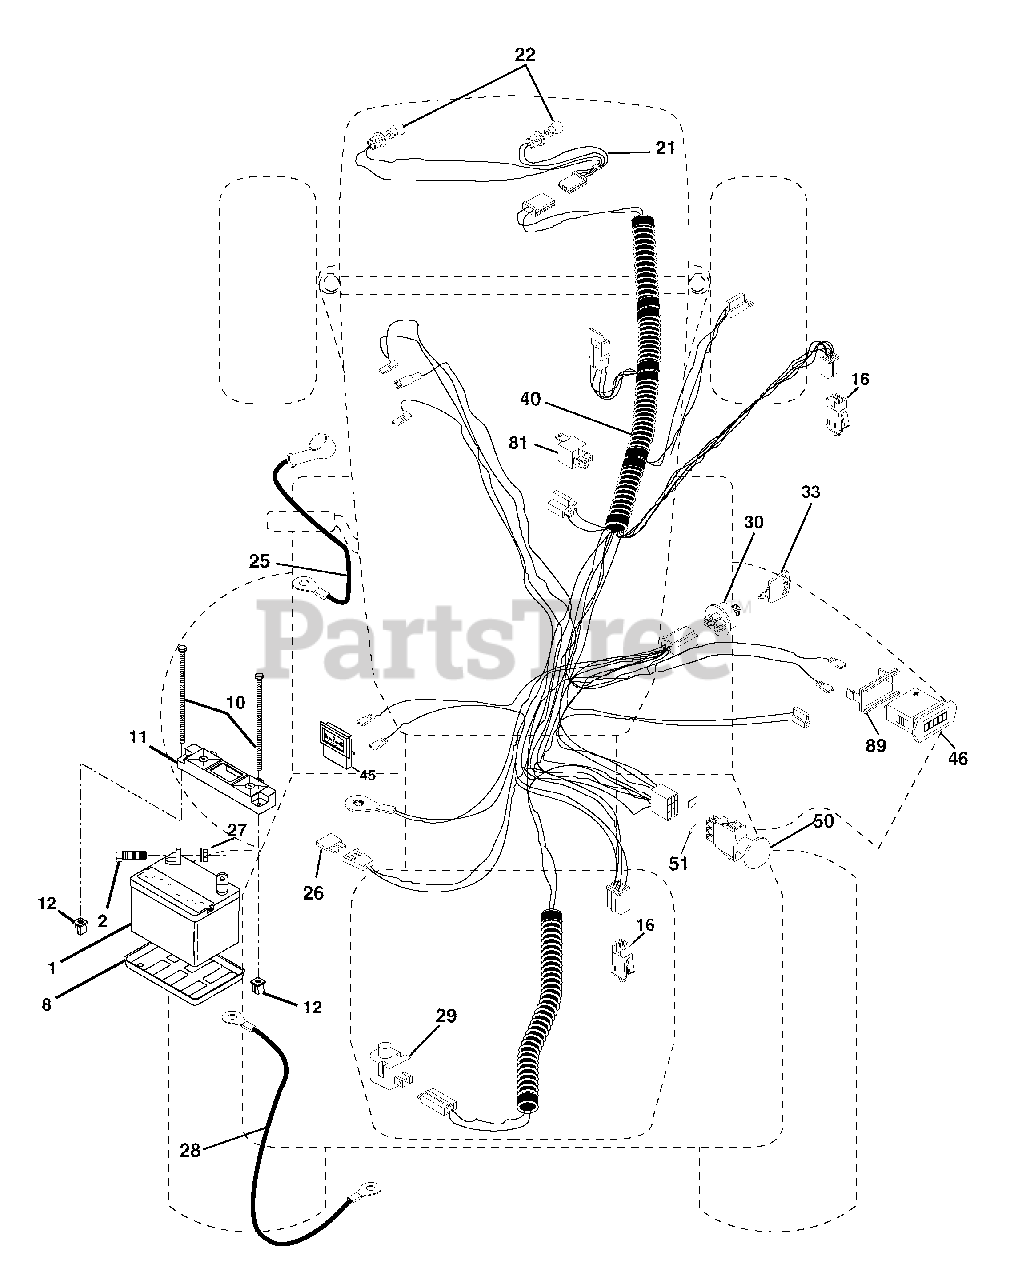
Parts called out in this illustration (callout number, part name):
1	Battery
2	Bolt Hex Head 1/4-20 x 3/4
8	Tray, Battery
10	Bolt, Battery Front 1/4-20 x 7.5 Zinc
11	Holddown Battery Front Mount
12	Nut, Push Nylon 1.4" Battery Front
16	Switch Interlock Push-In
21	Harness Socket Light w/4152J
22	Bulb Light
25	Cable, Boot Asm CV25 W/16 WI
26	Fuse
27	Nut Keps Hex 1/4-20 Unc
28	Cable,Ground
29	Switch, Plunger Normal Op Olive
30	Switch, Ign
33	Key
40	Harness Ign.
45	Ammeter Rectangular
46	Meter, Hour
50	Switch, PTO
51	Ring Retainer PTO
81	Relay Asm.
89	Bracket Snap-In Hourmeter
